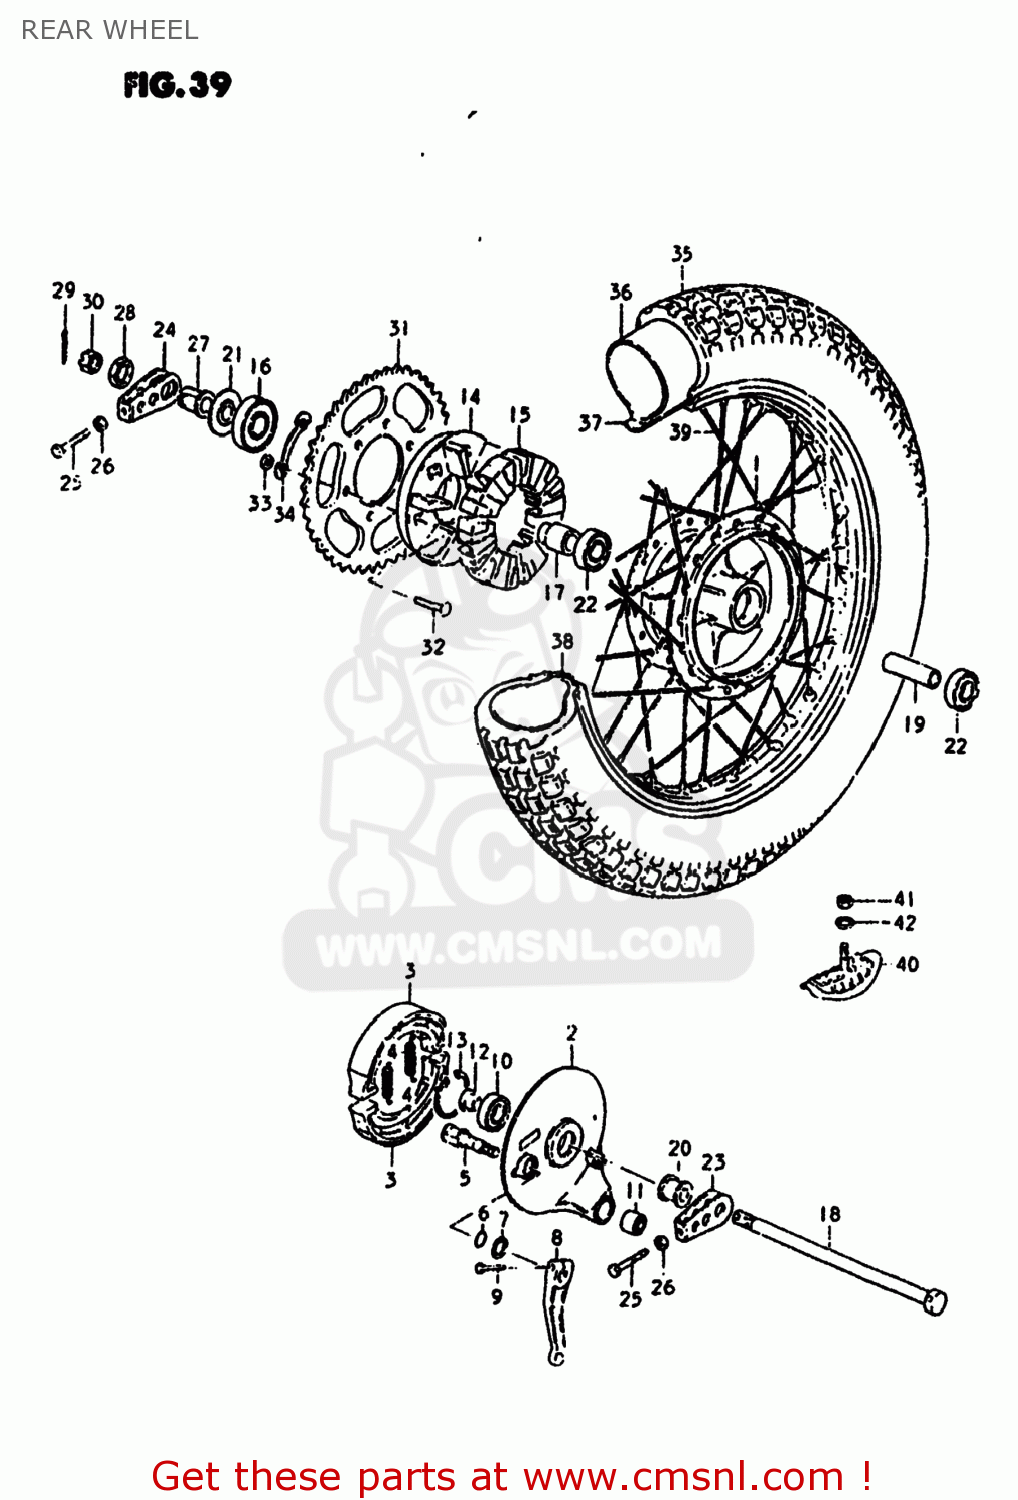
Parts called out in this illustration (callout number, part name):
1	DRUM,REAR HUB
2	PANEL,REAR HUB
3	SHOE,BRAKE (MCA)
4	SPRING
5	CAM,FRONT BRAKE
6	O-RING,BOSS
7	WASHER (15X24X1.6)
8	LEVER,REAR BRAKE CAM
9	BOLT
10	BALL BEARING
11	BUSH
12	SPACER,REAR HUB PANEL
13	CIRCLIP,42MM
14	DRUM,REAR SPROCKET MOUNT
15	CUSHION,REAR DRUM
16	BEARING
17	SPACER,REAR HUB BEARING
18	AXLE,REAR
19	SPACER (15.3X21.7X82)
20	SPACER,AXLE,RIGHT
21	SPACER,REAR AXLE,RIGHT
22	BEARING, RH
23	ADJUSTER,CHAIN
24	ADJUSTER,CHAIN
25	BOLT
26	NUT
27	SPACER,CHAIN ADJUSTER
28	NUT
29	PIN 30X40
30	NUT
31	SPROCKET,REAR
32	BOLT(8X33.5)
33	NUT
34	WASHER
35	TIRE
36	TUBE,INNER
37	PROTECTOR,WHEEL,INNER
38	RIM,REAR WHEEL
39	SPOKE SET,RR
40	STOPPER,BEAD
41	NUT
42	WASHER
